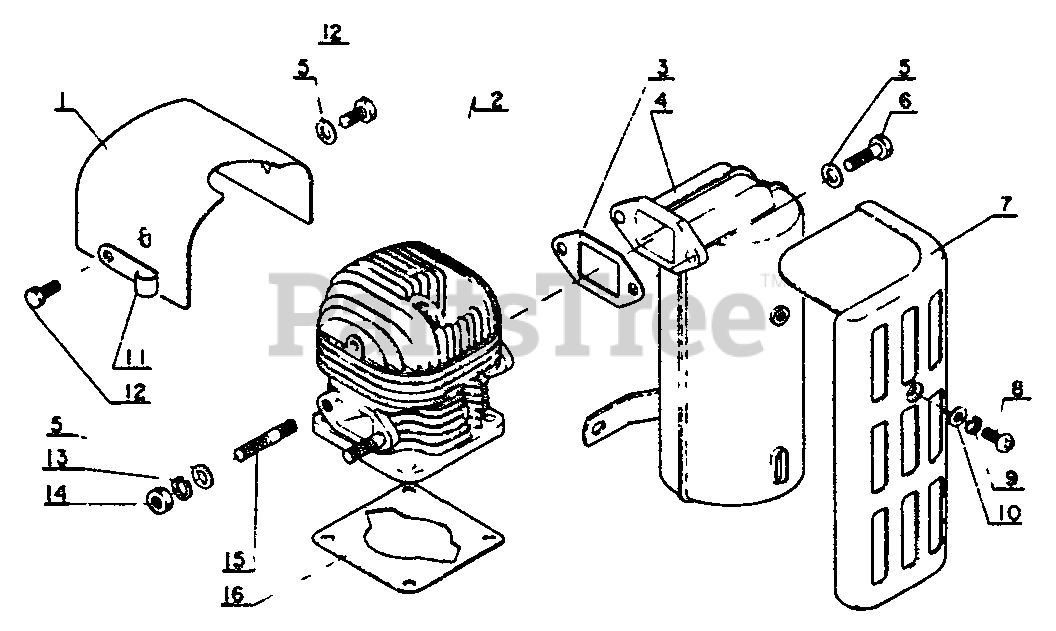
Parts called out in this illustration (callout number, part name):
1	SHIELD, CYLINDER
2	CYLINDER
3	GASKET, EXHAUST
4	MUFFLER
5	WASHER - 6
6	BOLT - 6X20
7	COVER, MUFFLER
8	SCREW - 5X12
9	LOCKWASHER - 5
10	WASHER - 5
12	BOLT - 6X10
13	LOCKWASHER - 6
14	LOCKNUT - 6
15	STUD
16	GASKET, CYLINDER
